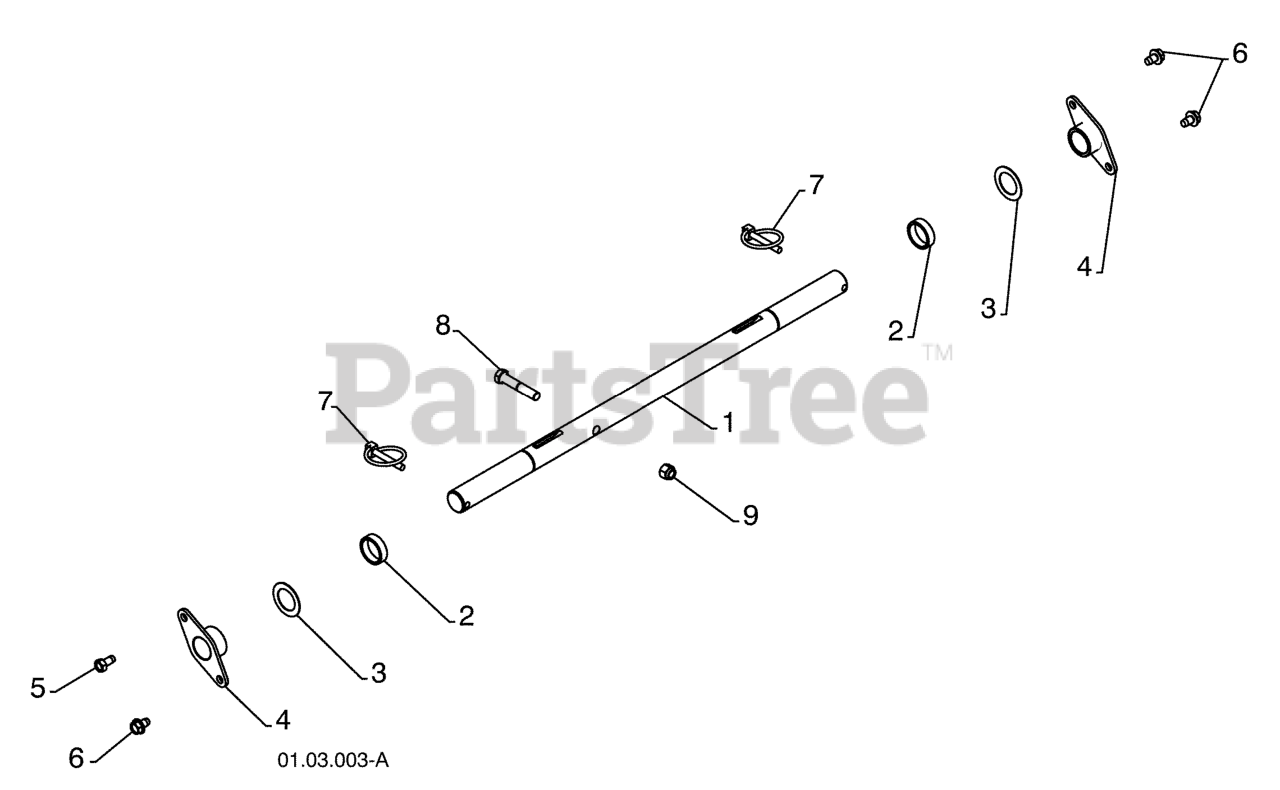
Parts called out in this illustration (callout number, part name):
1	SHAFT.AXLE.POWER.STEERING.HYD
2	SPACER.AXLE.RH
3	WASHER TRUST 1"
4	BEARING, AXLE
6	BOLT 5/16-18 X .500
7	PIN KLIK, 1/4
8	CAP.SCREW.HEX.HD.3/8-16
9	NUT
